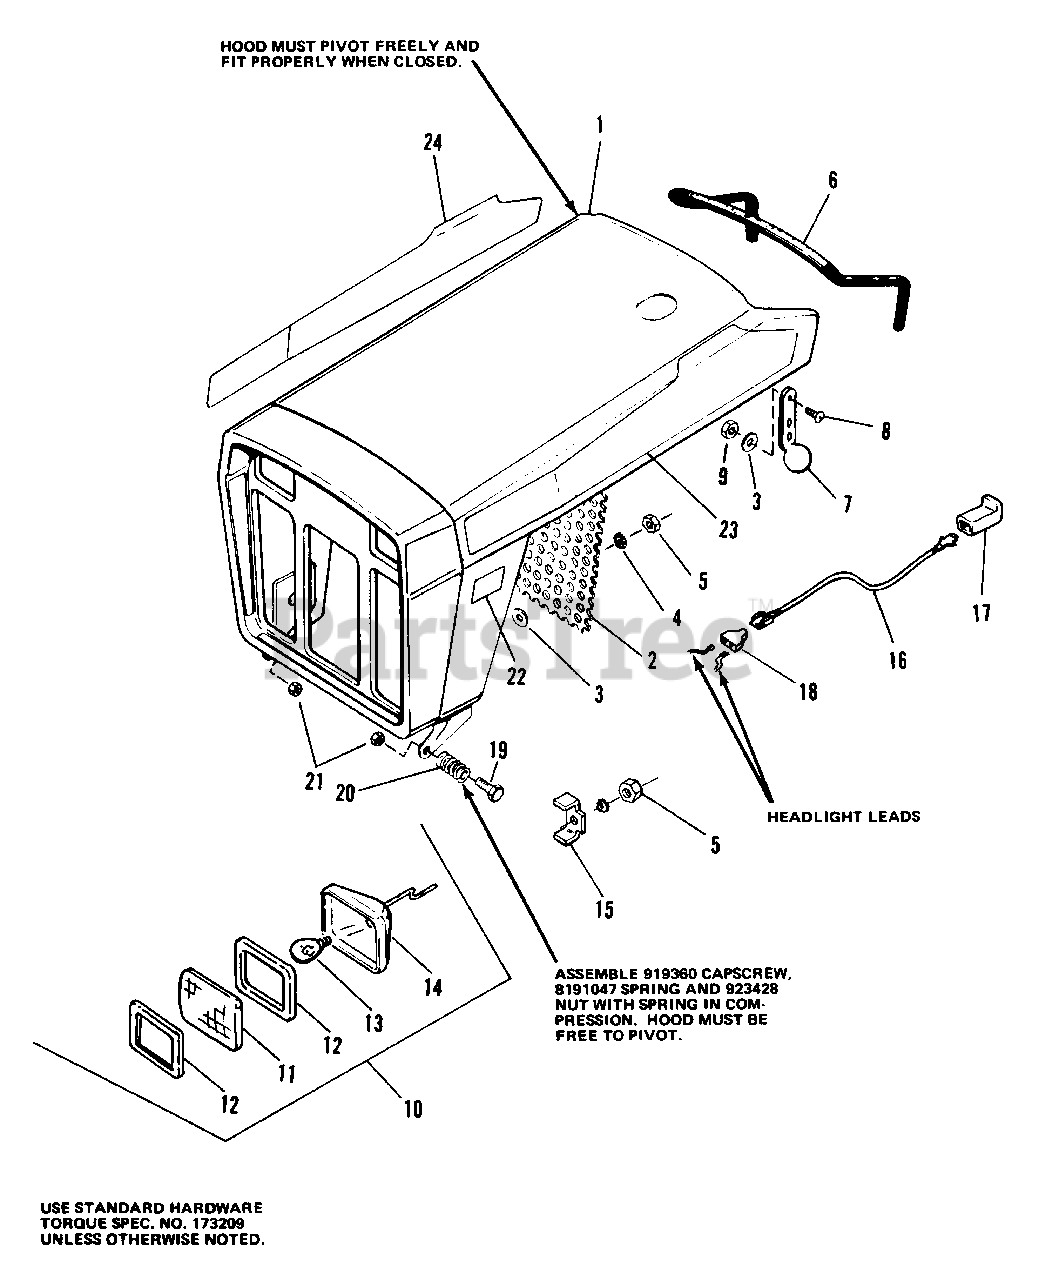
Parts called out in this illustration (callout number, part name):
1	HOOD & GRILLE ASSEMBLY
2	SCREEN, Grille
3	WASHER, Special
4	LOCKWASHER, Ext. Tooth, No. 10
5	NUT, Hex, Mach., No. 10-24
6	MOULDING, Hood
7	STRAP, Hood
8	SCREW, Truss Hd., No. 10-32 x 1/2
9	LOCKNUT, Hex, No. 10-32
16	WIRE ASSY
17	BODY, Connector
18	CONNECTOR, Insulated
19	CAPSCREW, Hex, Hd., 3/8-16 x 1-1/2
21	NUT, Hex, Center Lock, 3/8-16
22	DECAL, 7014 Shuttle
23	DECAL, Hood, Baron, L.H.
24	DECAL, Hood, Baron, R.H.
